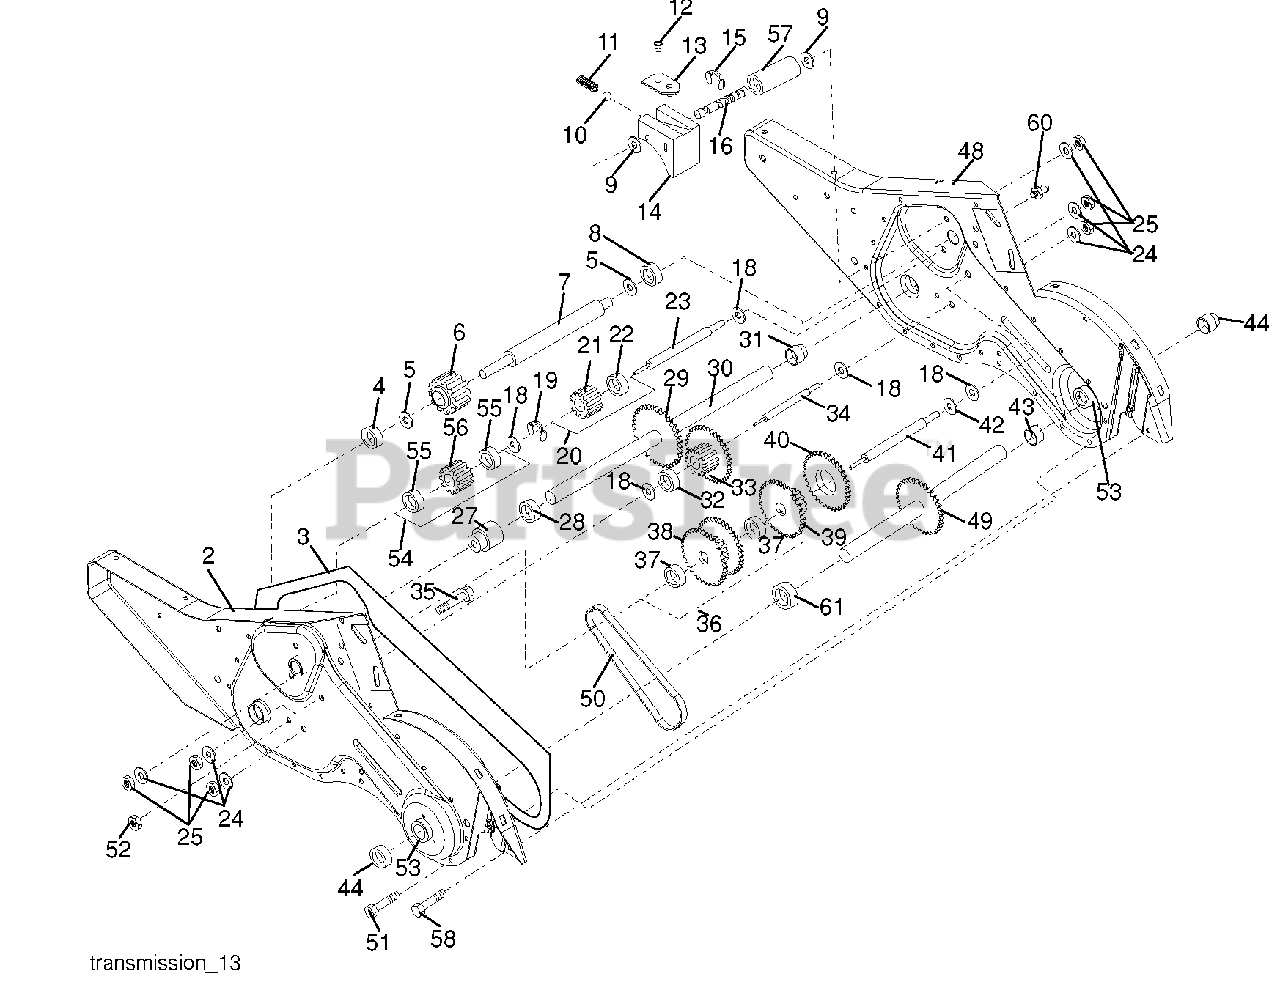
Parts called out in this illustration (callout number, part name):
1	Trans mis sion Assembly
2	Gearcase, L.H. w/Bearing
3	Gasket, Gearcase
4	Bearing, Needle
5	Washer, Thrust 5/8 x 1.10 x 1/32
6	Pinion, Input
7	Shaft, In put
8	Bearing, Needle
9	Washer, Seal
10	Ball, Steel
11	Spring, Shift, Fork
13	Arm, Shift
14	Fork, Shift
15	Ring, Klip
16	Shaft, Shift
19	Ring, Klip
20	Gear, Assembly, Reverse Idler
21	Gear, Re verse Idler
22	Bearing, Needle
23	Shaft, Reverse Idler
24	Washer, Lock 7/16
25	Nut, Hex 7/16-20
27	Bearing, Shaft, Ground Drive L.H.
28	Spacer 0.765 x 1.125 x 1.23
29	Chain #35-50 Pitch
30	Ground Shaft Assembly
31	Bearing, Shaft, Ground Drive R.H.
32	Spacer 0.70 x 1.00 x 1.150
33	Sprocket and Gear Assembly
34	Shaft, Re duc tion (2nd)
35	Screw, Whiz, Lock 5/16-18 x 3-1/2
36	Sprocket Assembly w/Bearing
37	Bearing, Needle
38	Sprocket, Tine
39	Gear, Clus ter, Red 1st & 2nd
40	Gear, Re verse
41	Shaft, Re duc tion (1st)
42	Washer, Thrust
43	Spacer 1.01 x 1.75 x 0.760
44	Seal Asm. OIl
48	Gearcase, R.H. w/Bearing
49	Shaft, Tine
50	Chain, Roller #50-50 Pitch
51	Screw 1/4-20 x 1/2
52	Nut, Hex 5/16-18
53	Bearing Kit, Tine Shaft
54	Gear, DRT Idler w/Bearing
55	Bearing, Needle
56	Gear, DRT Idler
57	Spacer, Split .52 x .64 x 1.04
58	Screw 1/4-20 x .875
60	Fitting Grease
61	Spacer 1.015 x 1.50 x .656
